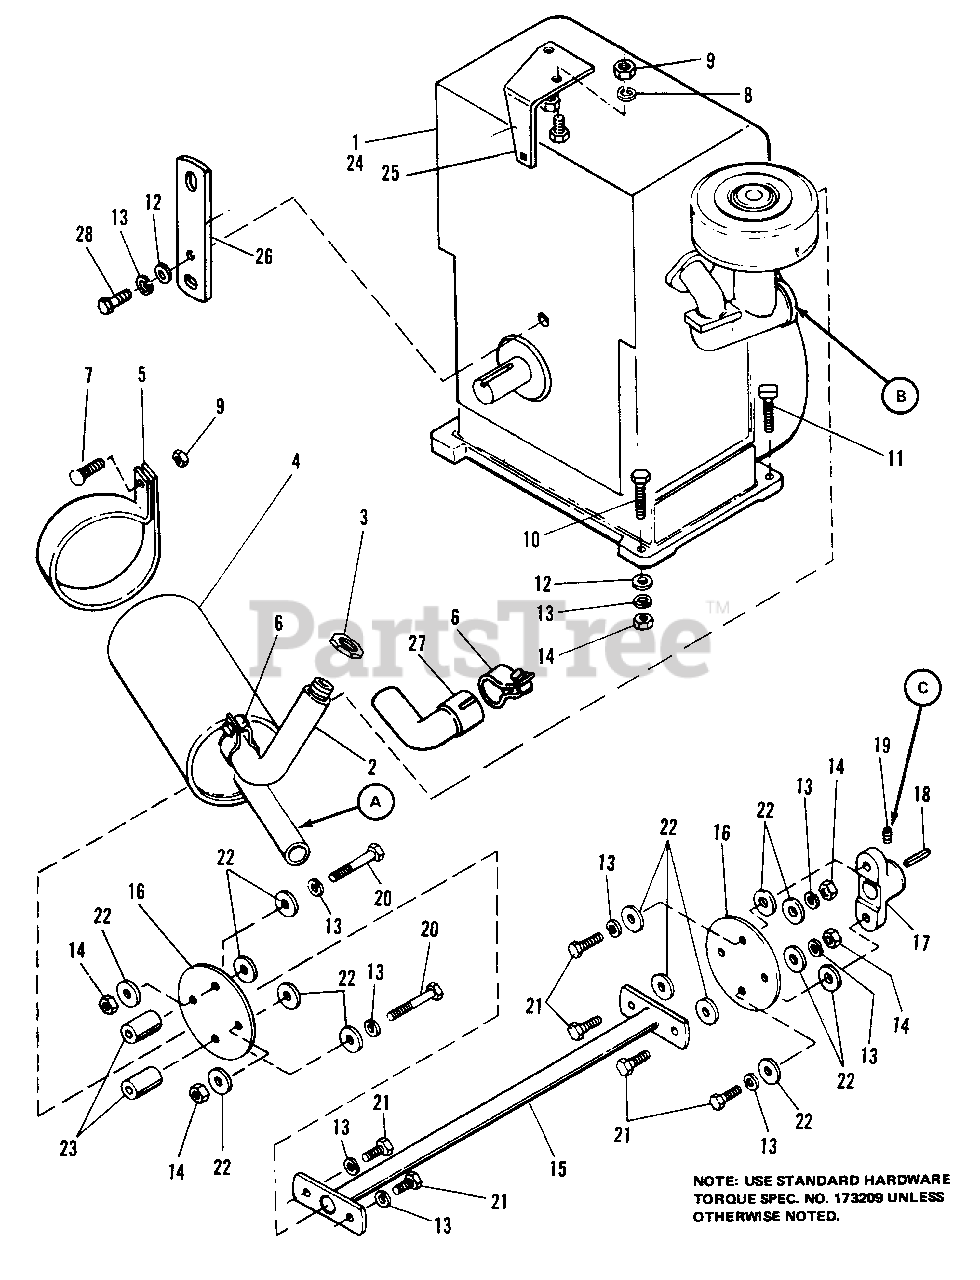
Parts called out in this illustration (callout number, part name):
1	ENGINE, 10 H.P., Kohler
2	ELBOW & NIPPLE ASSY (7016 Only)
3	LOCKNUT (7016 Only)
5	STRAP, Muffler
6	CLAMP, Muffler (Quan. 1 used on 7016 )
7	CAPSCREW, Hex Hd., 5/16-18 x 1-1/2 (7010 Only)
8	LOCKWASHER, 5/16 (Used on 7016 Only)
9	LOCKNUT, Hex, Flange, Whizlock, 5/16-18 (Quan. 1 used on 7010)
10	CAPSCREW, Hex Hd.,3/8-16 x 1-1/2 (Quan. 2 used on 7016)
11	CAPSCREW, Rect. Hd,3/8-16 x 1-5/6 (7016 0nly)
12	WASHER,3/8 (Quan. 4 used on 7016)
13	LOCKWASHER, 3/8 (Quan. 12 used on 7016 )
14	NUT, Hex, 3/8-16
15	DRIVE SHAFT ASSY
17	FLANGE, Drive Shaft
18	KEY, Drive Shaft
19	SETSCREW, 3/8-24 x 3/8
20	CAPSCREW, Hex Hd., 3/8-16 x 2-1/4
21	CAPSCREW, Hex Hd., 3/8-16 x 1-1/4
22	WASHER, Special
24	ENGINE, 16 H.P., Briggs & Stratton
25	SUPPORT, Muffler (7016 Only)
26	BRACKET (7010 Only)
27	ELBOW (7010 Only)
28	CAPSCREW, Hex Hd., 3/8-16 x 7/8 (7010 Only)
